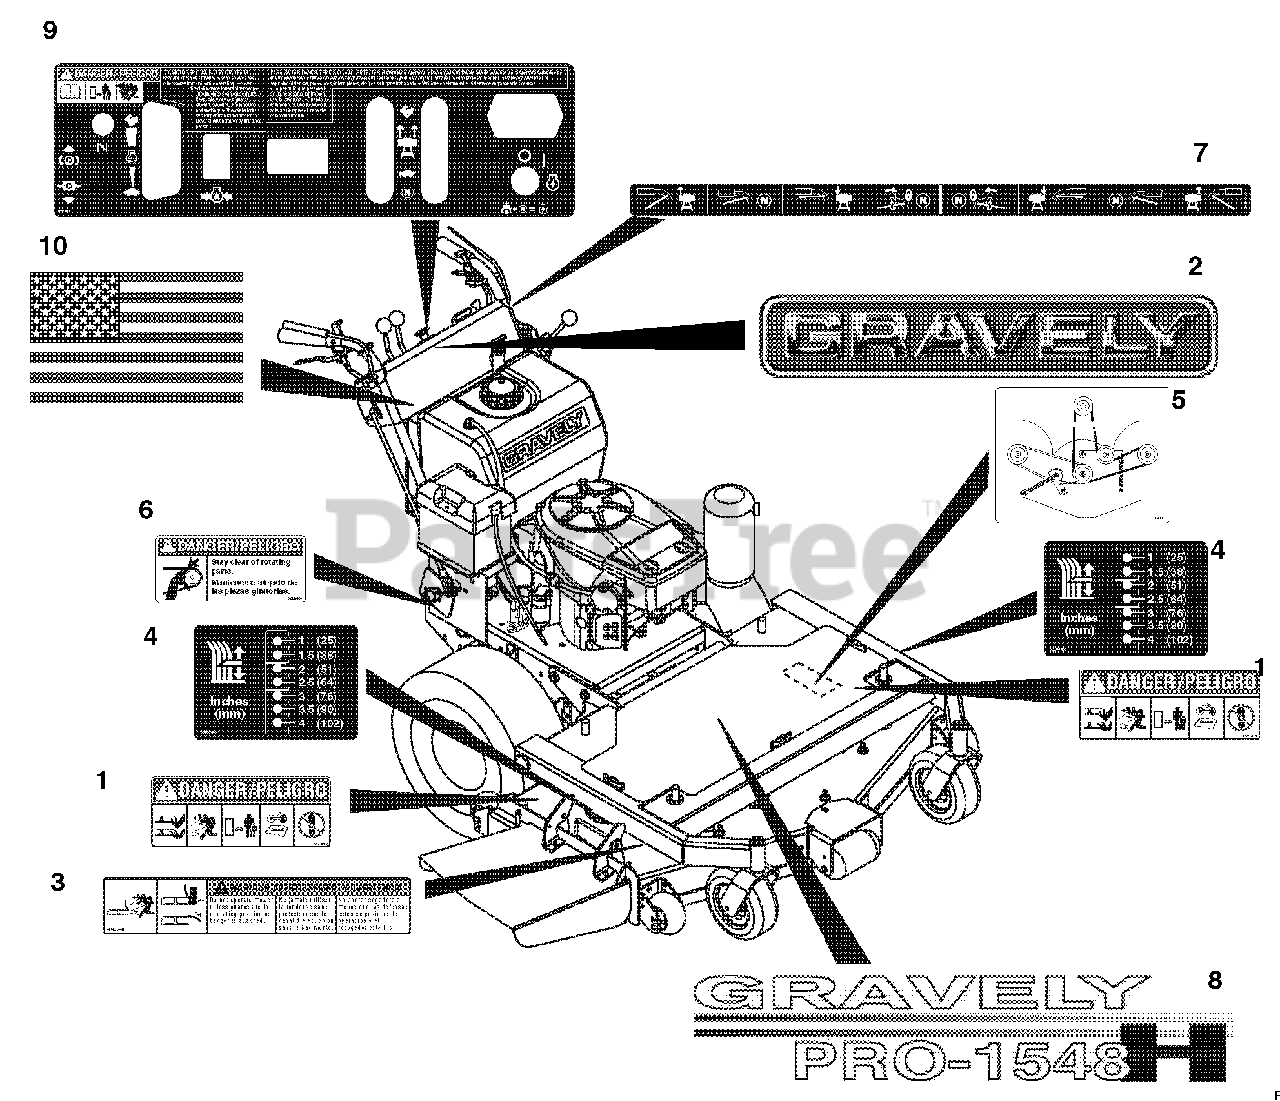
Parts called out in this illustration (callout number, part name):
1	Decal, Mower Pan Head Danger
2	Decal- 15" Gravely Logo
3	Decal, Warning
4	Decal-Height of Cut- Floating
5	Decal-Belt Diagram-3 Spindle
6	Decal-Danger-Belt Rotating
7	Decal, Steer Levers (107, 108, 109)
8	Decal-Pro 1548H (107)
9	Decal, Control HE17 (108, 109)
10	Decal, American Flag
